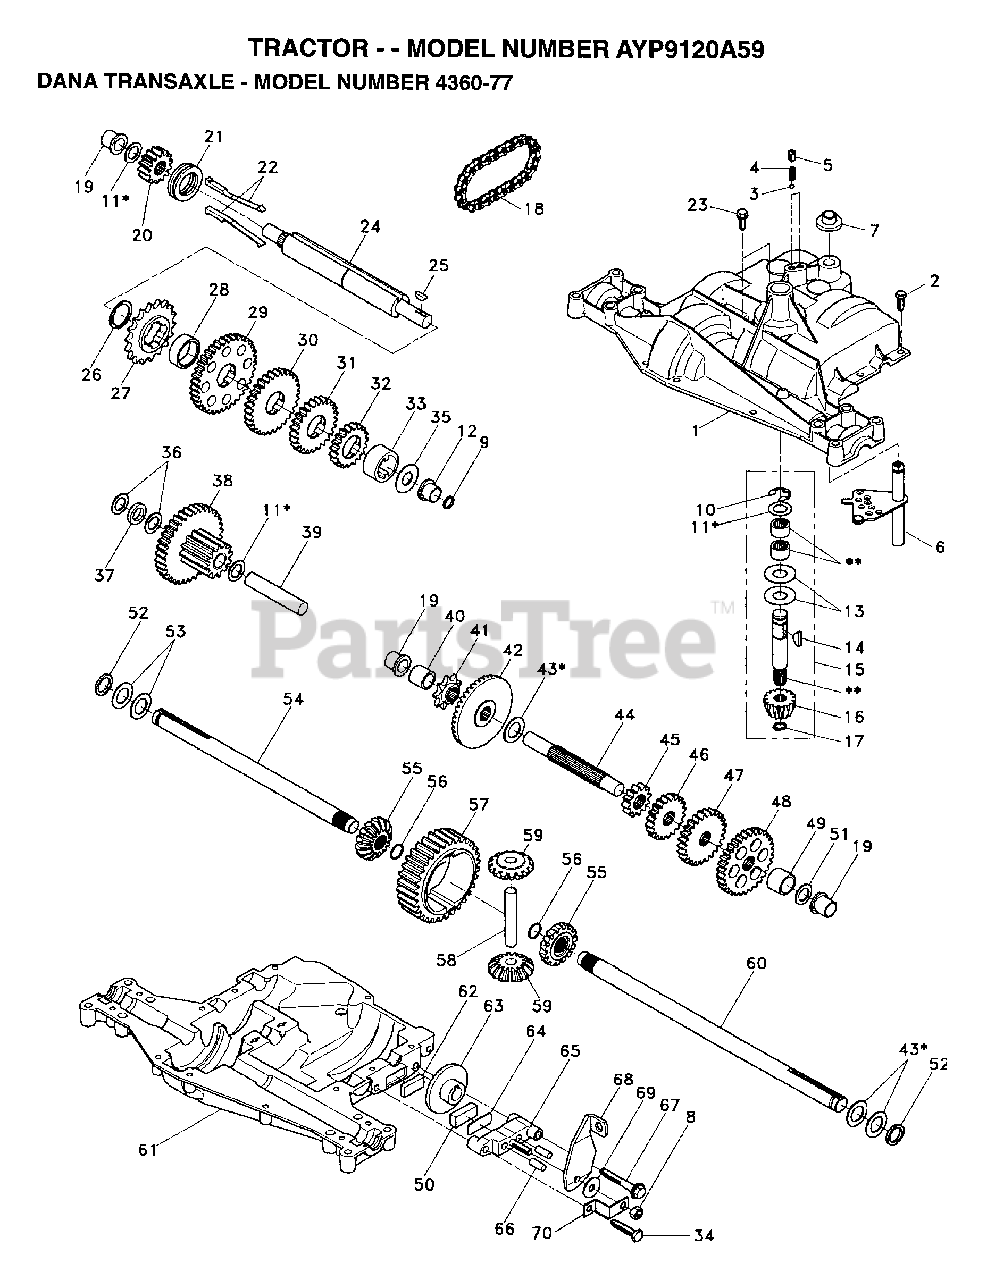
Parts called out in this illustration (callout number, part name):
1	HOUSING, UPPER
3	BALL, DETENT
4	SPRING, DETENT
5	SCREW, SET
6	SHIFTER ASSEMBLY
7	BOOT, SHIFTER
8	LOCKNUT 5/16-24
10	RING, RETAINING
11	ASSY, KIT, SHIM .625 SHAFT
12	BEARING, FLANGE
13	WASHER, PLAIN .632 X 1.38 X .046
14	KEY, WOODRUFF, #9
15	ASSEMBLY, KIT, INPUT SHAFT
16	PINION, BEVEL, 14 TEETH
17	RING, RETAINING
18	CHAIN, 24 PITCHES
19	BEARING, FLANGE
20	GEAR, SPUR, 14 TEETH
21	COLLAR, CLUTCH
22	ASSEMBLY, KIT, CLUTCH KEYS
23	SCREW TAPPING WITH SEALER
24	SHAFT, INTERMEDIATE
25	KEY, WOODRUFF, #61
26	RING, RETAINING
27	SPROCKET, 18 TEETH
29	GEAR, SPUR, 37 TEETH
30	GEAR, SPUR, 30 TEETH
31	GEAR, SPUR, 25 TEETH
32	SPACER 1.133 X 1.50 X .750
33	GEAR, SPUR, 22 TEETH
34	SCREW TAPPING
35	WASHER, PLAIN .640 X 1.37 X .061
36	WASHER, PLAIN .632 X 1.00 X .026
37	SPACER .630 X 1.00 X .169
38	ASSY GEAR COMB 12&35 TEETH
39	SHAFT, IDLER
40	SPACER .635 X .875 X .755
41	SPROCKET, 9 TEETH
42	GEAR, BEVEL, 42 TEETH
43	ASSY, KIT, SHIM .750 SHAFT
44	SHAFT, DRIVE
45	GEAR SPUR, 12 TEETH
46	GEAR, SPUR, 20 TEETH
47	GEAR, SPUR, 25 TEETH
48	GEAR, SPUR, 31 TEETH
49	SPACER .781 X 1.00 X .750
50	PUCK, FRICTION
51	WASHER, PLAIN .632 X 1.00 X .060
52	WASHER, NEOPRENE
53	WASHER, PLAIN .758 X 1.25 X .031
54	AXLE LEFT HAND
55	GEAR, MITER, 15 TEETH
56	RING, RETAINING
57	GEAR, SPUR, 32 TEETH
58	SHAFT, CROSS
59	GEAR, MITER, 15 TEETH
60	AXLE, R.H.
61	HOUSING, LOWER
62	PUCK, FRICTION
63	DISC, BRAKE
65	JAW, BRAKE
66	PIN, DOWEL
67	SCREW, SELF-TAPPING
68	LEVER ACTUATING
69	WASHER, PLAIN .321 X 1.00 X .055
70	BRACKET, ANTI-ROTATION
